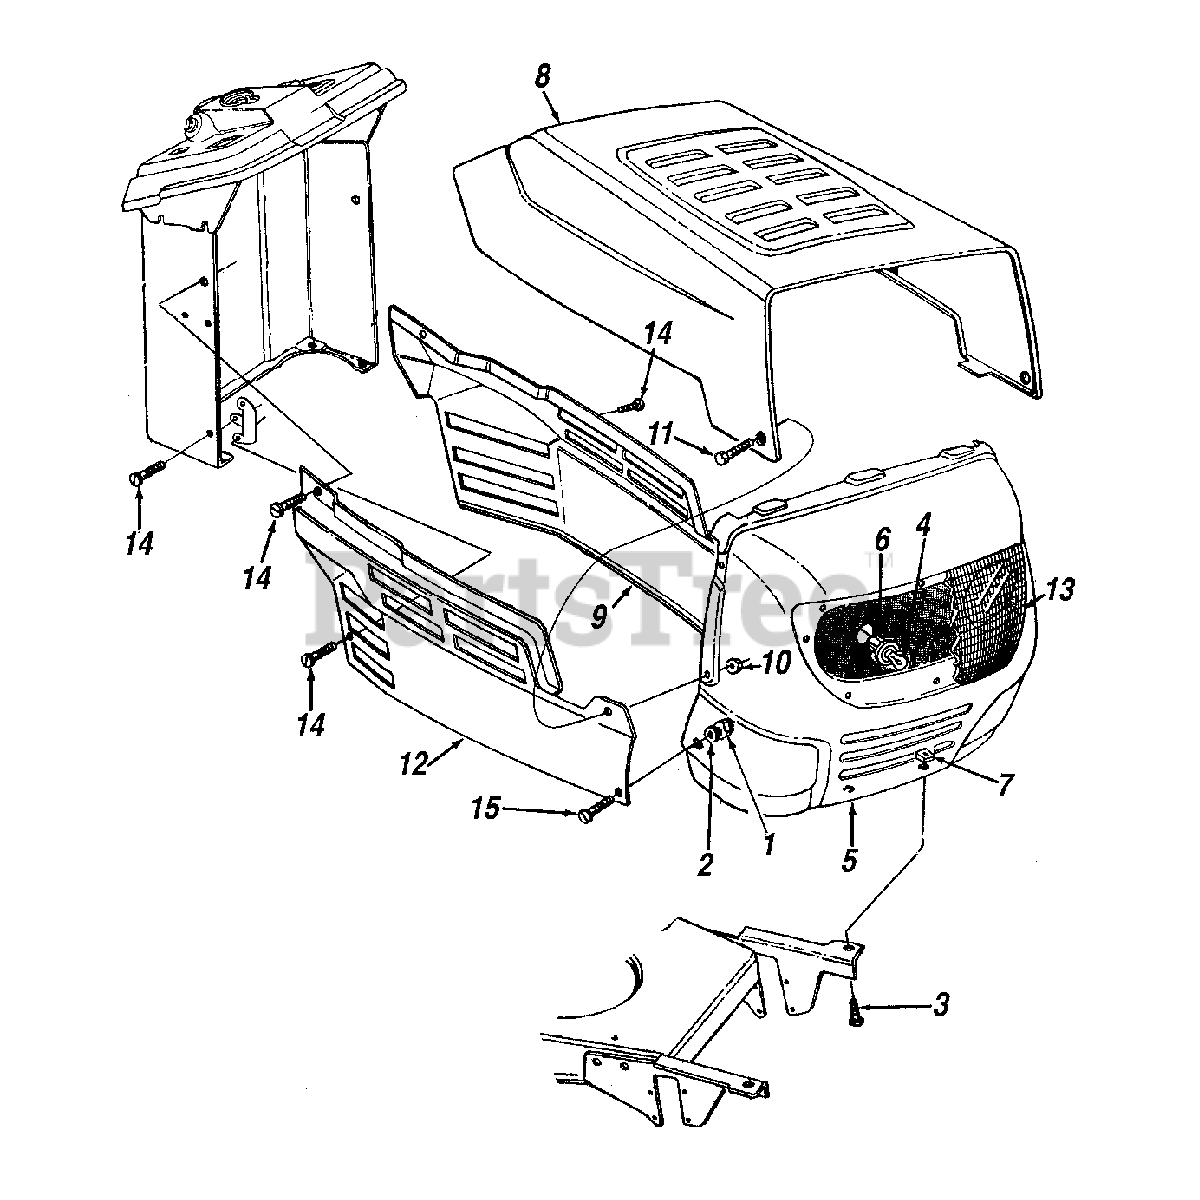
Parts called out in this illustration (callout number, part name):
1	Hex Nut 1/4-20 Thd. (Gr. 5)
2	Bell-Washer 1/4" I.D.
3	Hex Bolt 5/16-18 x .75" Lg.
4	Bulb
6	Socket
7	U-Nut 5/16-18 Thd.
11	Shld. Bolt
14	Hex Tap Scr. 1/4-20 x .5" Lg.
15	Pan Hd. Mach. Scr. 1/4-20 x .5" Lg.
